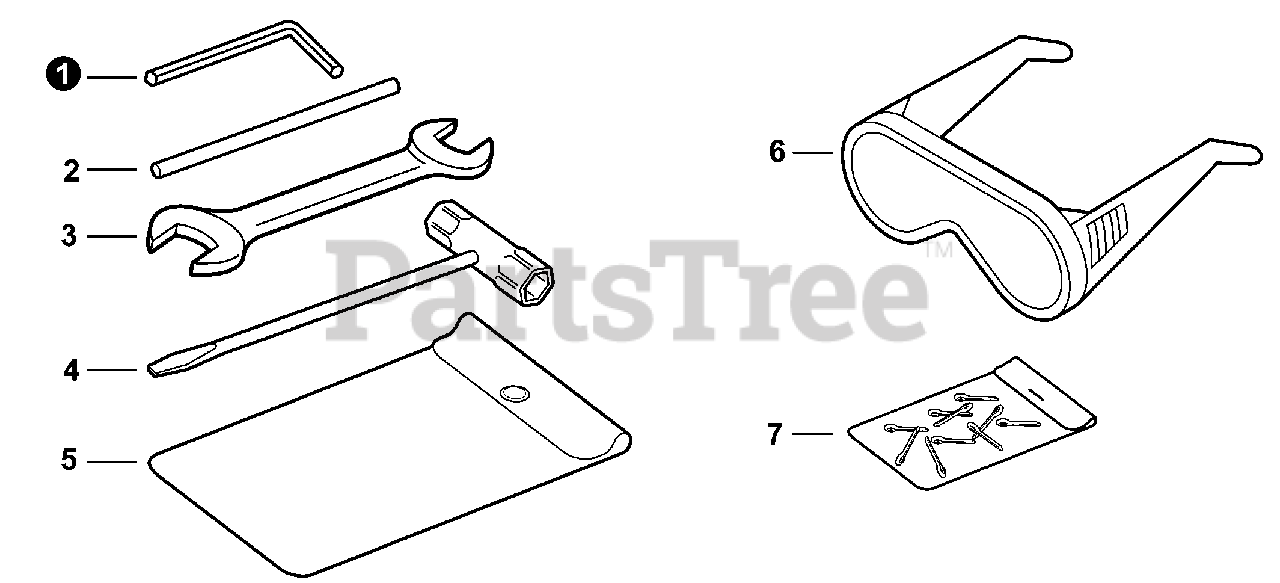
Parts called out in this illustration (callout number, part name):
1	WRENCH, ALLEN T27 80×30
2	TOOL, LOCKING 5×120mm
3	SPANNER 8×10
4	T-WRENCH 17×19 L200
5	BAG, TOOL
6	GLASSES, SAFETY
7	PIN, COTTER 2×22
